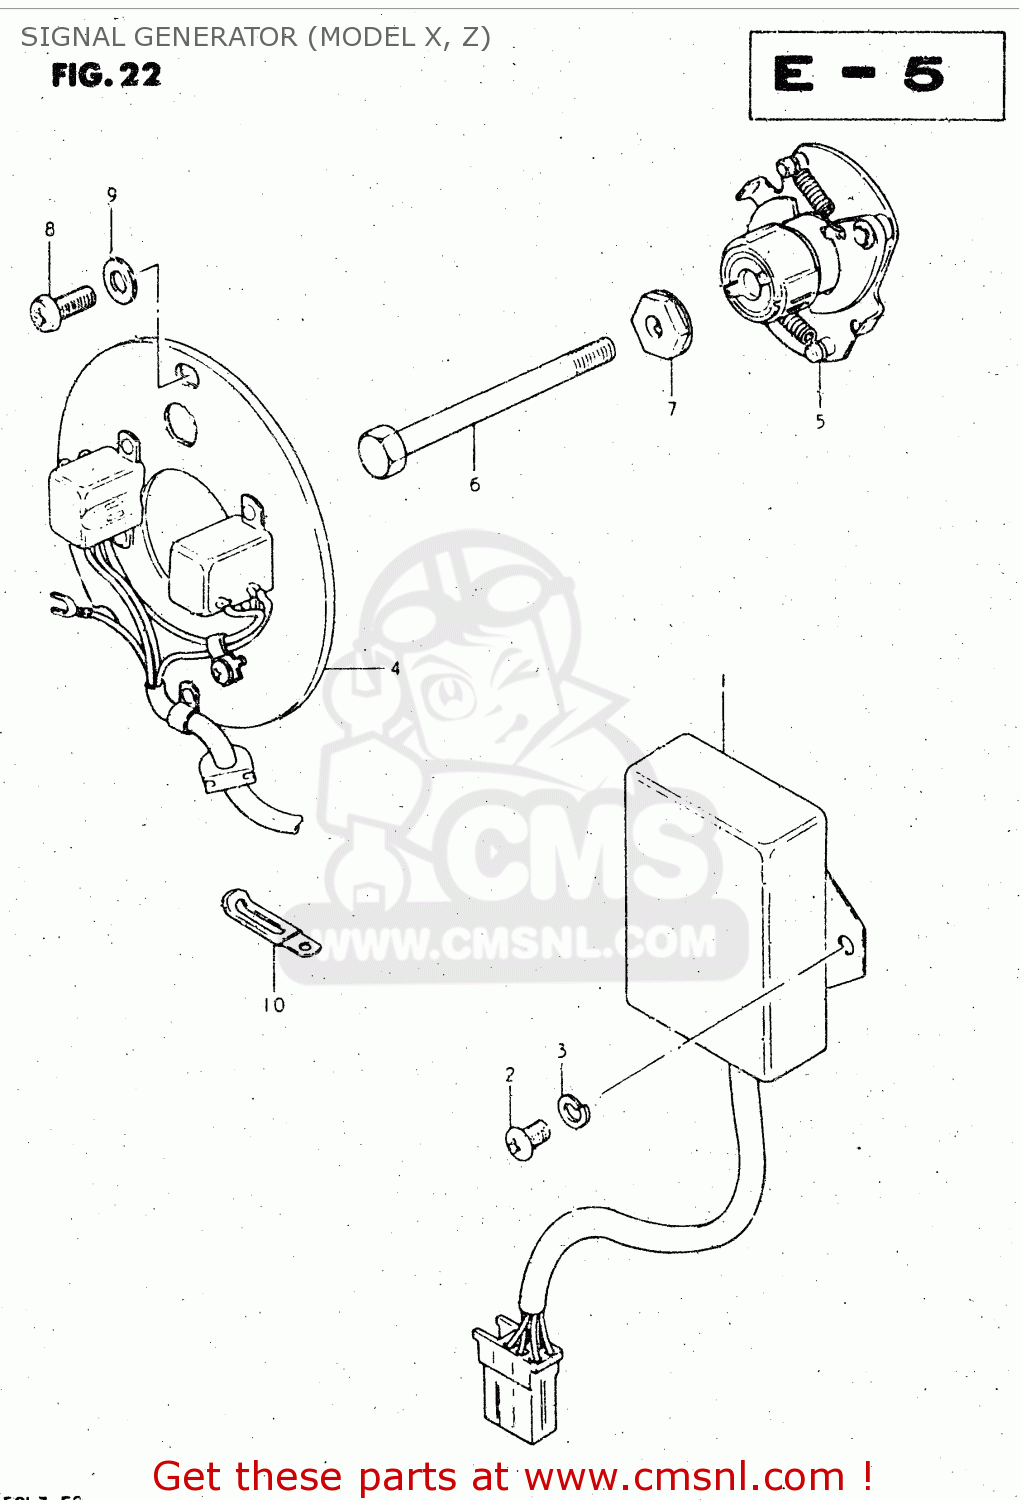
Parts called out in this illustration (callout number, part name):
1	CDI UNIT KOKUSAN
2	SCREW
3	LOCK WASHER
4	SIGNAL GENERATOR ASSEMBLY
5	GOVERNOR ASSEMBLY
6	BOLT 6X60
7	WASHER,CONTACT BREAKER
8	SCREW(5X12)
9	WASHER
10	CLAMP L:35
